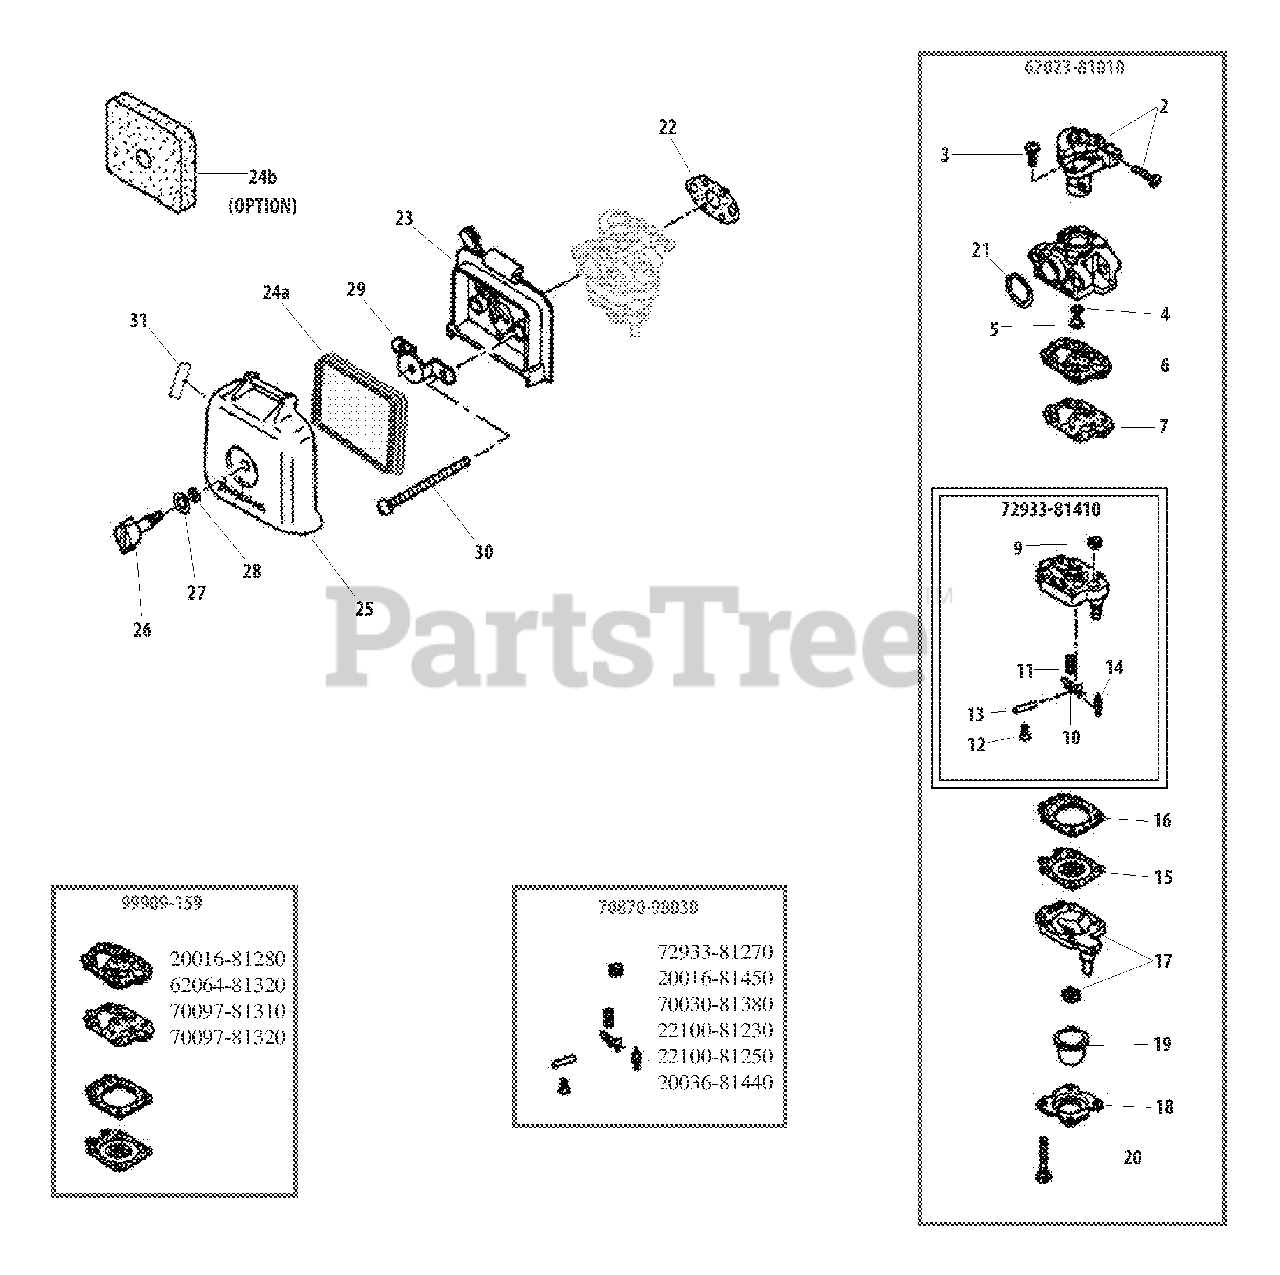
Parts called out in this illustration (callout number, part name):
2	VALVE ASSY, THROTTLE
3	SCREW, THROTTLE COLLAR
4	O-RING
5	JET, MAIN
6	GASKET, PUMP
7	DIAPHRAGM, PUMP
9	SCREEN, FUEL INLET
10	LEVER, METERING
11	SPRING, METERING LEVER
12	SCREW
13	PIN, METERING LEVER
14	VALVE, INLET NEEDLE
15	DIAPHRAGM ASSY
16	GASKET, METERING DIAPHRAGM
17	BODY ASSY, PURGE
18	RETAINER, PURGE BULB
19	BULB, PURGE
20	SCREW
21	O-RING 15
22	GASKET, CARBURETOR
23	CASE, AIR FILTER
24A	FILTER, AIR
24B	FILTER, AIR
25	COVER, AIR FILTER
26	THUMBSCREW
27	O-RING
28	WASHER, CONE M6
29	BRACKET
30	SCREW - 5×67
31	LABEL, CHOKE
62023-81010	CARBURETOR
70870-98030	VALVE KIT, INLET NEEDLE
99909-159	GASKET / DIAPHRAGM KIT
